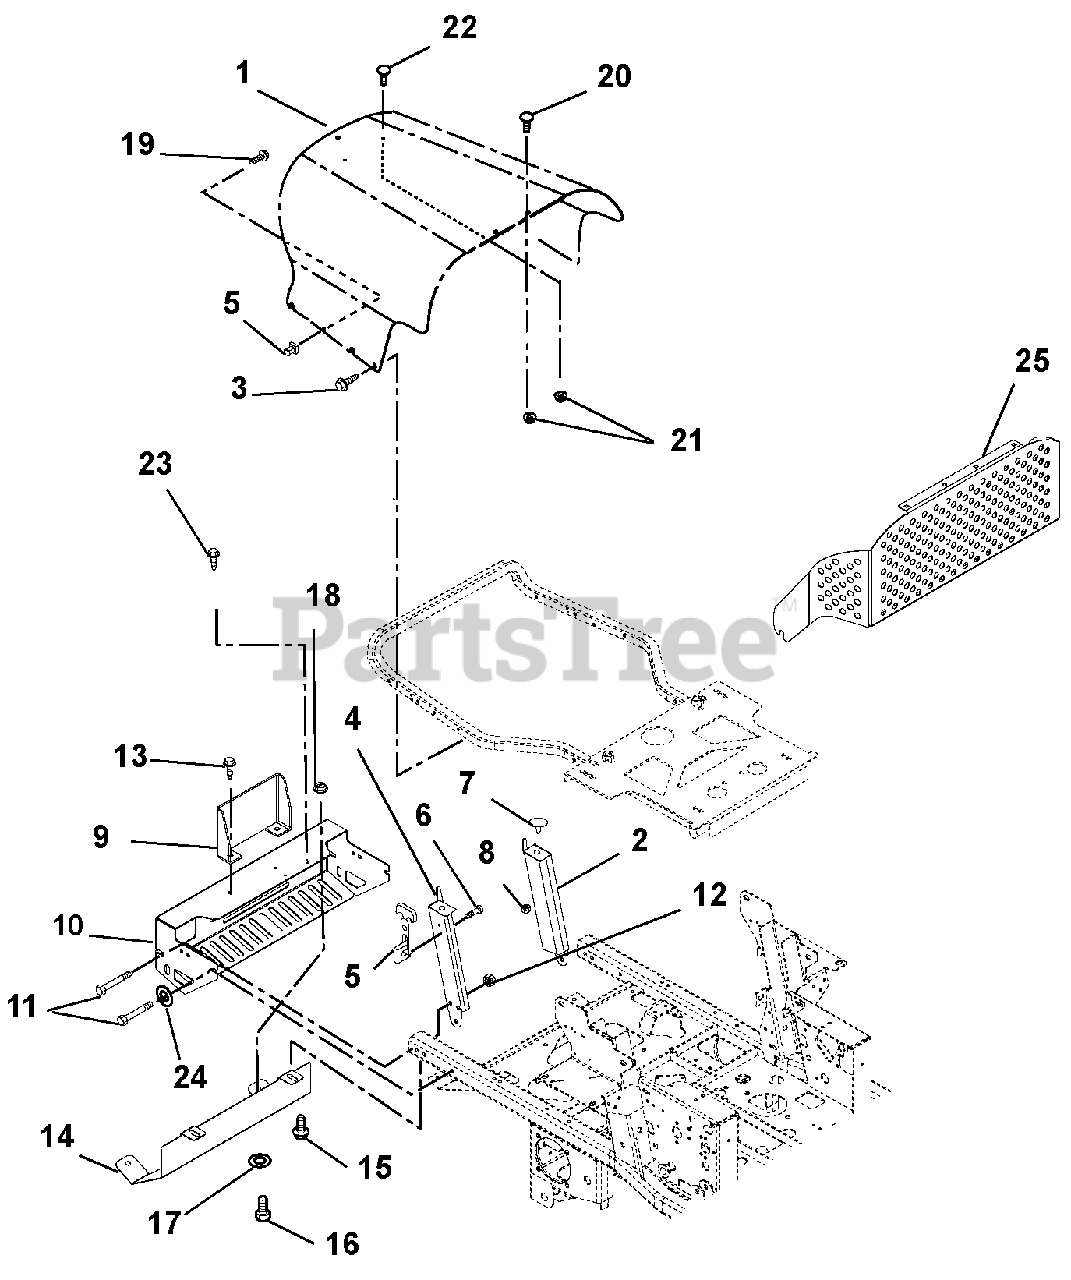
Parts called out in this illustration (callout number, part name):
2	Weldment, Hood Support, Left Hand
3	Screw, Tapping .38-16 x .75 Hex Washer Head
4	Weldment, Hood Support Right Hand
5	Latch, Rubber
6	Screw, Machine 10-24 x .50 Hex Washer Head
7	Button Bumper
8	Nut, Spin Lock Flange .312-18
9	Guard, Muffler
10	Bumper, Rear
11	Bolt, Hex .38-16 x 2.75 Grade 5
12	Nut, Locking Top Flange .38-16
13	Screw, Tapping .38-16 x .75 Hex Washer Head
14	Heat Shield
15	Screw, Tapping .38-16 x .50 Hex Washer Head Thread Rolling YWZ
16	Bolt, Hex .38-16 x .75 Grade 5
17	Washer, Flat Steel .438 x1.00 x .083 YWZ
18	Nut, Locking Top Flange .38-16
19	Screw, Machine 10-24 x 1.50 Hex Washer Head
20	Bolt, Round Head Square Neck .25-20 x .50 Grade 5
21	Nut, Locking Top Flange .25-20
22	Bolt, Round Head Square Neck .25-20 x .75 Grade 5
23	Screw, Tapping .25-20 x .50 Hex Washer Head Thread
24	Washer, Flat Steel .406 x .812 x .065
25	Plenum, Hood
